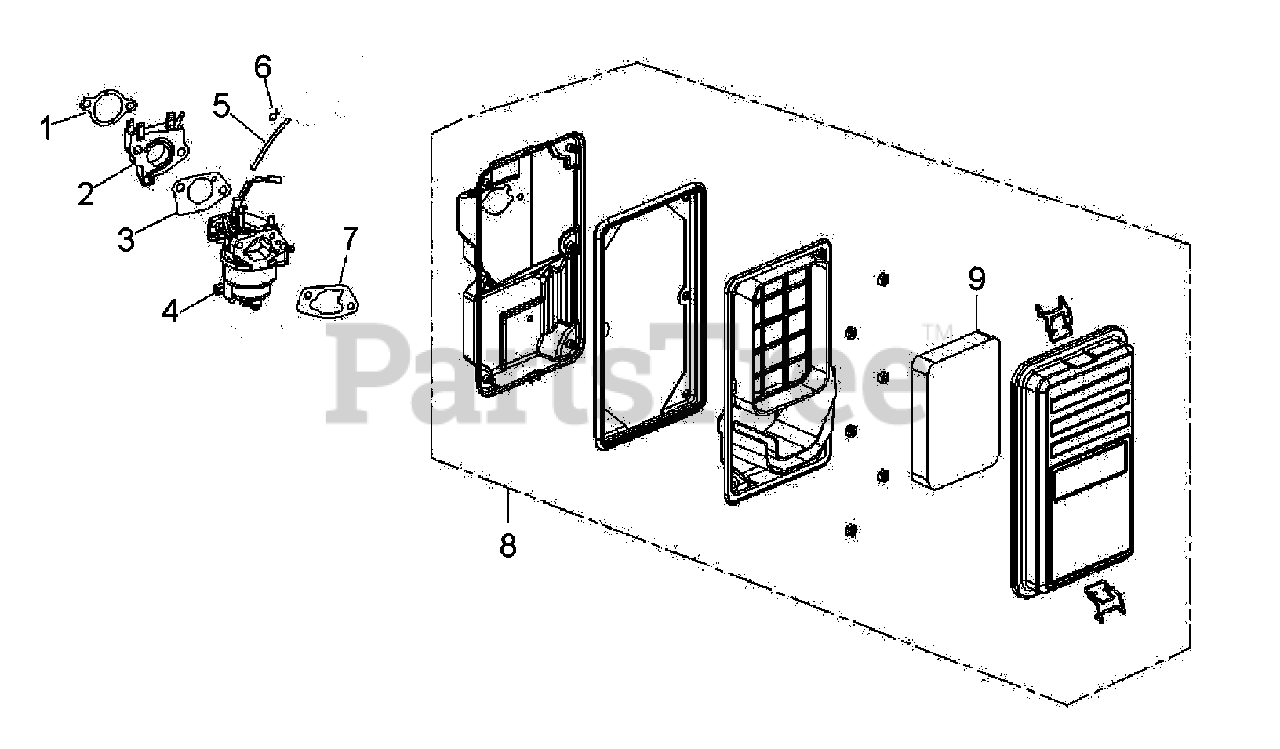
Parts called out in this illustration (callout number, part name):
1	GASKET' CARBURETOR
2	SPACER' CARBURETOR
3	GASKET' CARBURETOR
4	CARBURETOR ASSY.
5	TUBE' FUEL
7	GASKET' CARBURETOR
8	AIR CLEANER
9	ELEMENT' AIR CLEANER
